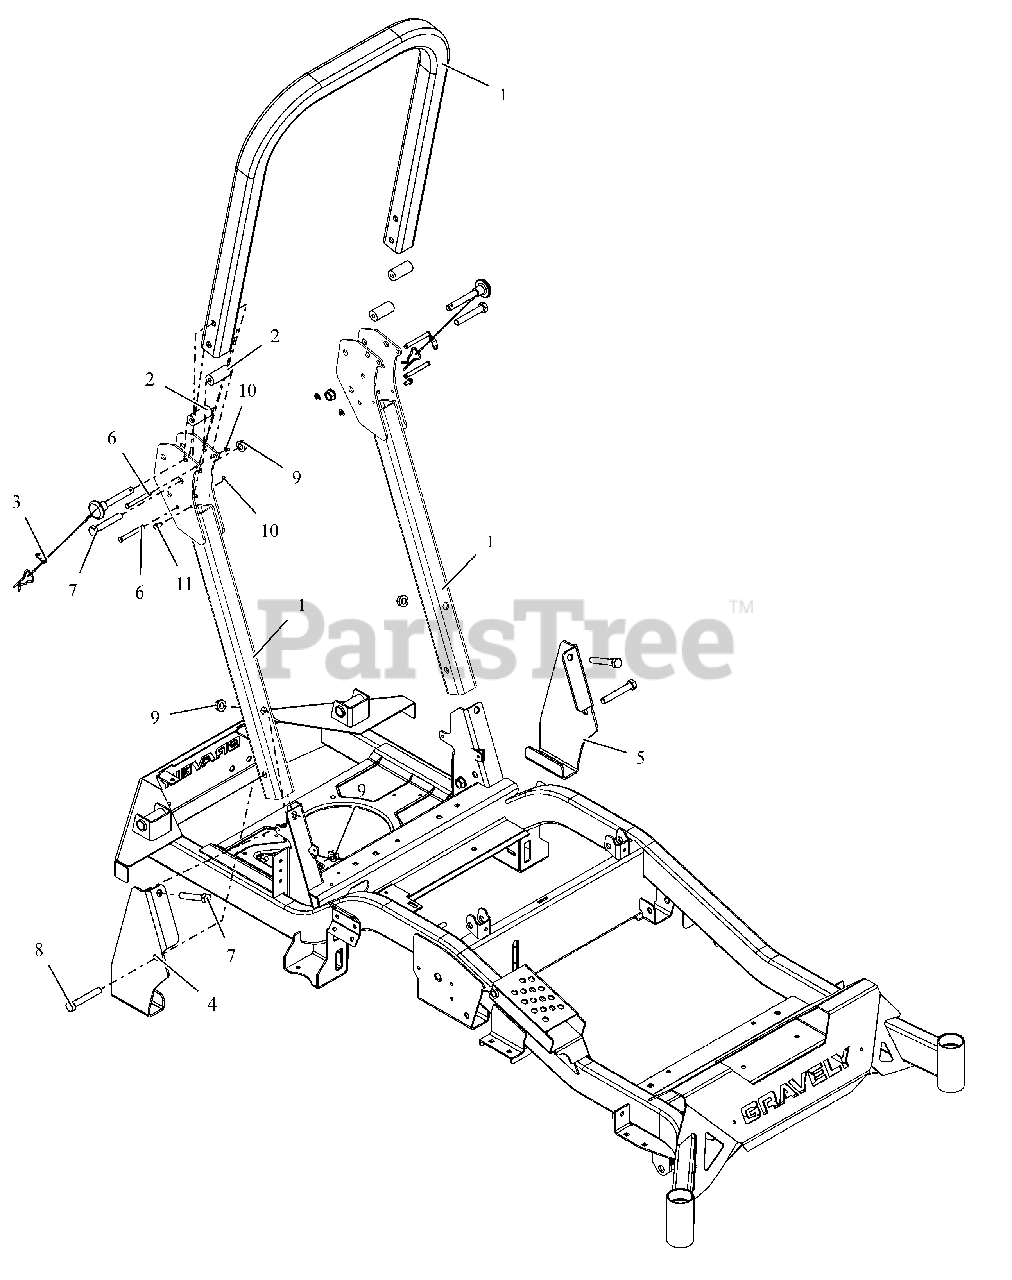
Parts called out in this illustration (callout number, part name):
1	ROPS, REPLACEMENT
2	BUMPER, ROPS ANTI-VIBRATION
3	PIN, ROPS W/LANYARD
4	BRKT, ROPS SUPPORT - RH
5	BRKT, ROPS SUPPORT -LH
6	PIN, 5/16 X 2-9/16 WITH GROOVE
7	BLT, HEX .50-13X3.00 G5 ZCC
8	BLT,HEX .50-13X3.25 G5 ZCC
9	NUT-LK-CTR-FLG .500-13 GG ZCC
10	RING, RETAINING-E .312 X .025
11	SCR-TAP .25-20X.50 HWH ZCC
